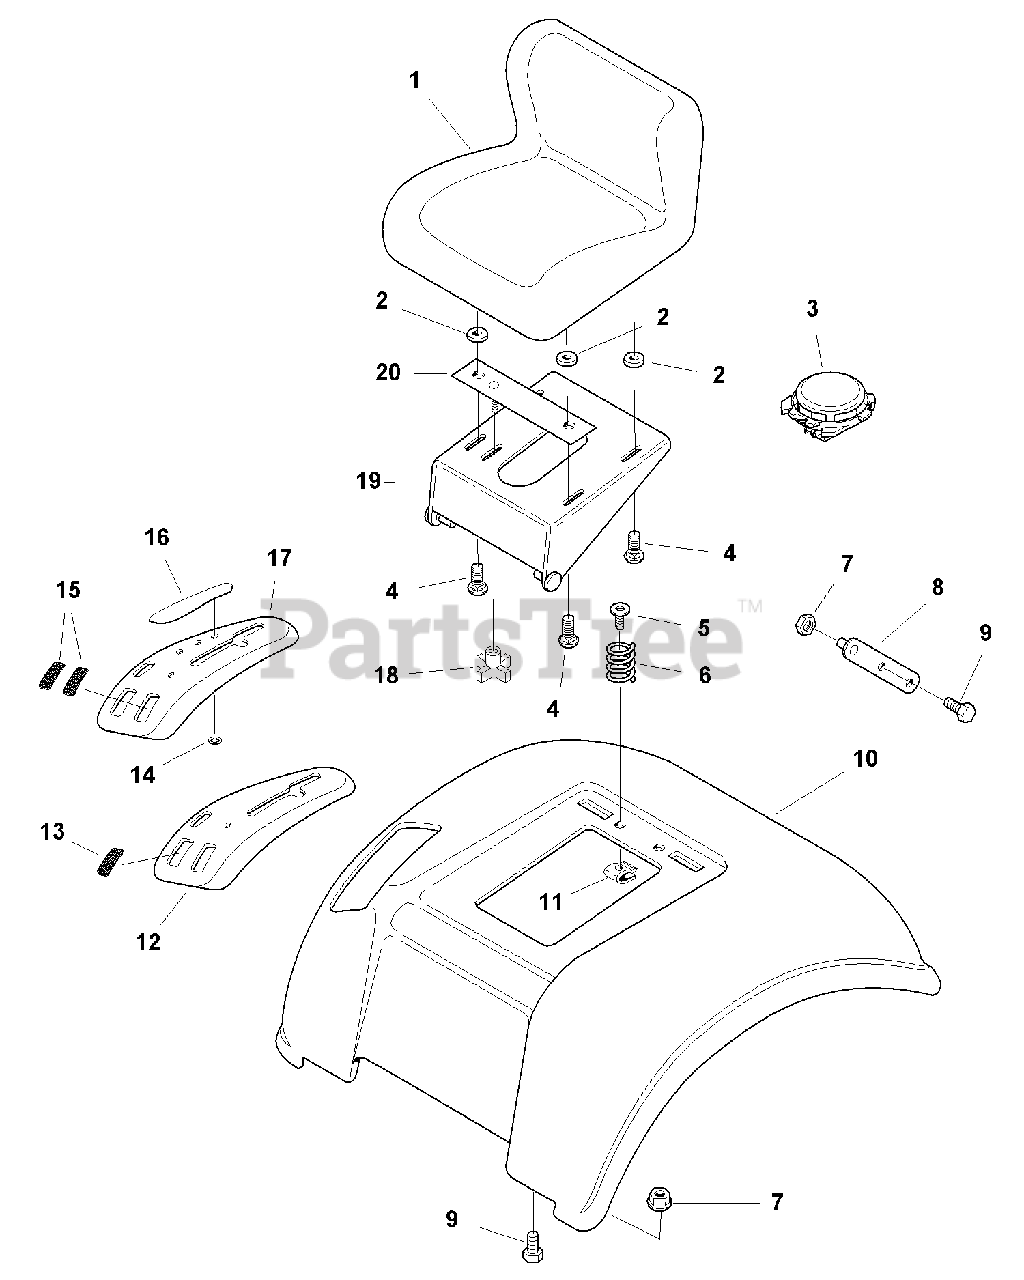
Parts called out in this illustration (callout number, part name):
1	SEAT
2	WASHER
3	SWITCH, Seat
4	CARRIAGE BOLT, 5/16-18 x 3/4
5	SCREW, Flat Head, 5/16-18 x 1-1/4
6	SPRING, Compression
7	NUT, Hex Head Whiz Lock, 5/16-18
9	CAPSCREW, Hex Head, 5/16-18 x 3/4
10	DECK, Seat, (Orange)
10	DECK, Seat, (Red)
11	NUT, Speed 5/16-18
12	POD, Seat for Gear
13	PLUG (Gear)
14	PUSH NUT(Hydro)
15	PLUGS (Hydro)
16	INSERT, Speed (Hydro)
17	POD, Seat for Hydro
19	SUPPORT & PIN ASSEMBLY
20	CLAMP & SCREW ASSEMBLY
